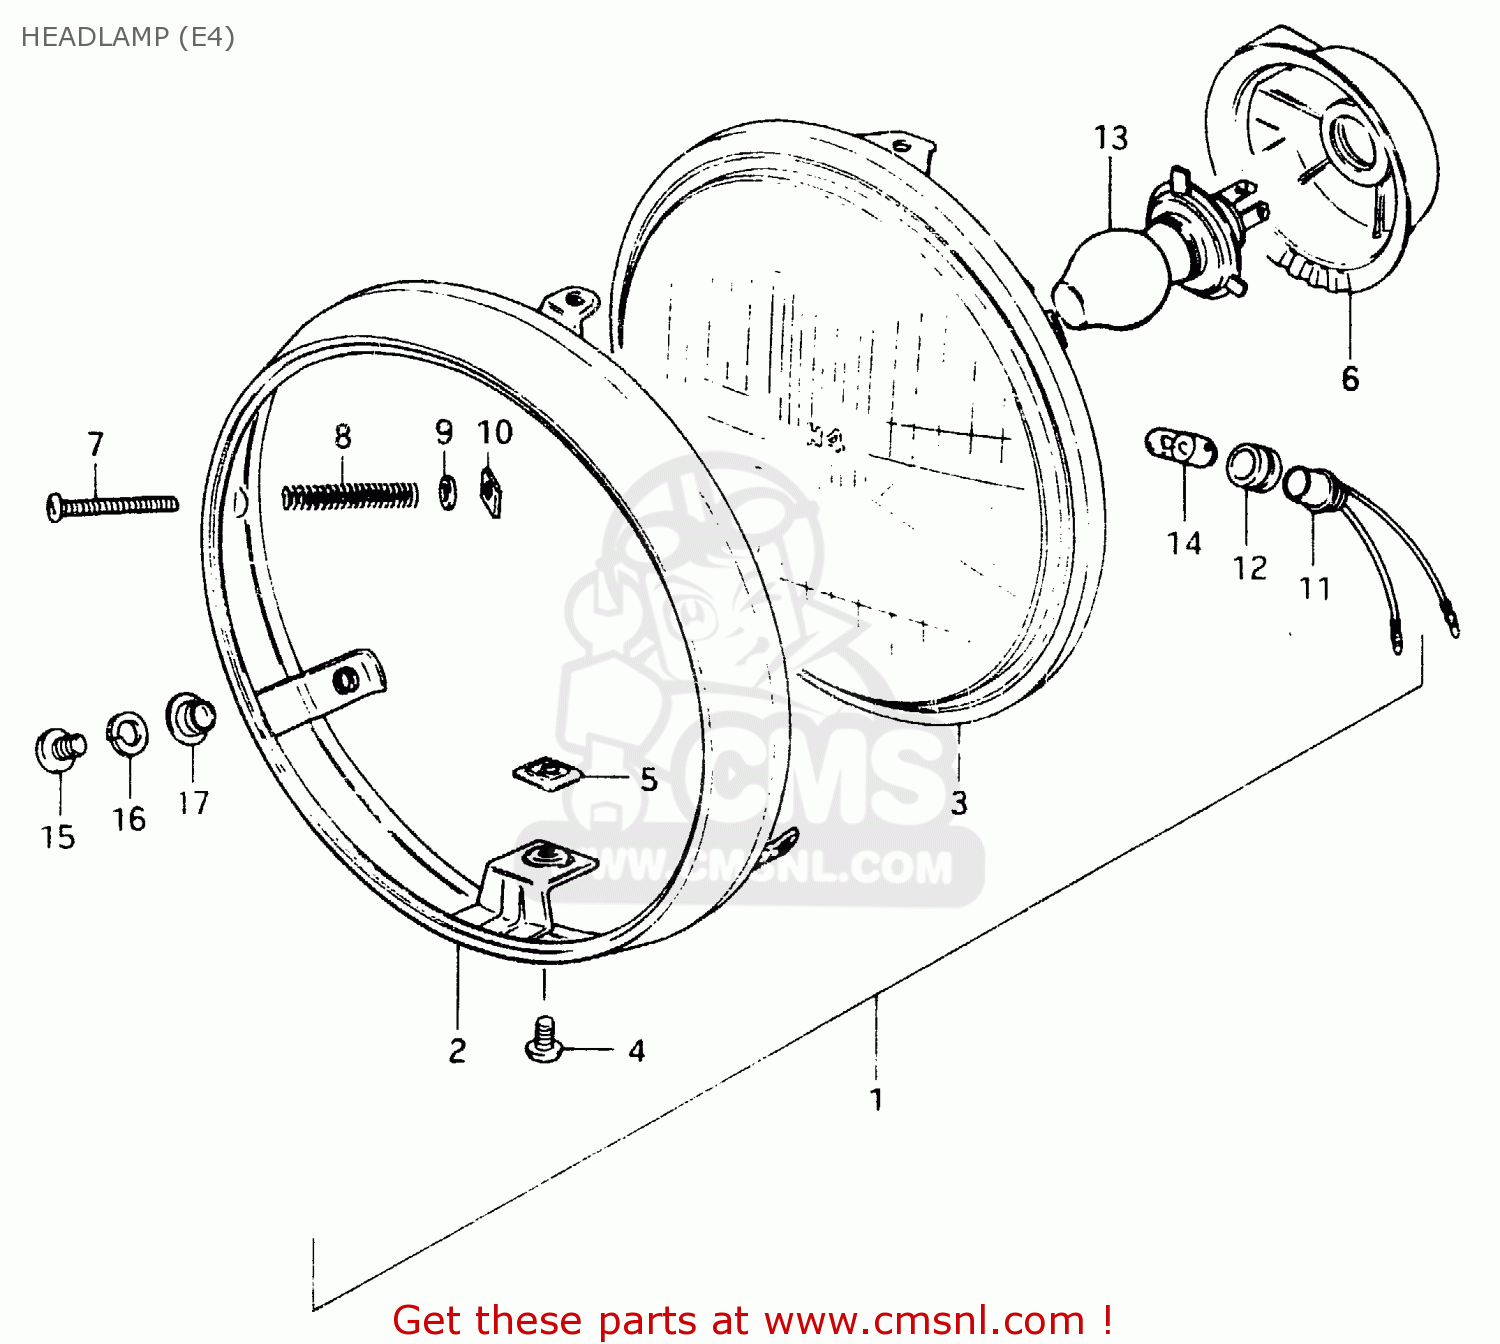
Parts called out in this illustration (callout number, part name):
1	HEADLAMP ASSY
2	RIM
3	LAMP UNIT
4	SCREW
5	NUT,ADJUSTING
6	COVER,SOCKET
7	SCREW,HEADLAMP ADJUST
8	SPRING
9	WASHER
10	NUT,HEADLAMP ADJUSTER
11	SOCKET
12	JOINT,RUBBER
13	BULB (12V, 60/55W, H4)
14	BULB(12V4W)
15	SCREW
16	WASHER,LOCK
17	WASHER
